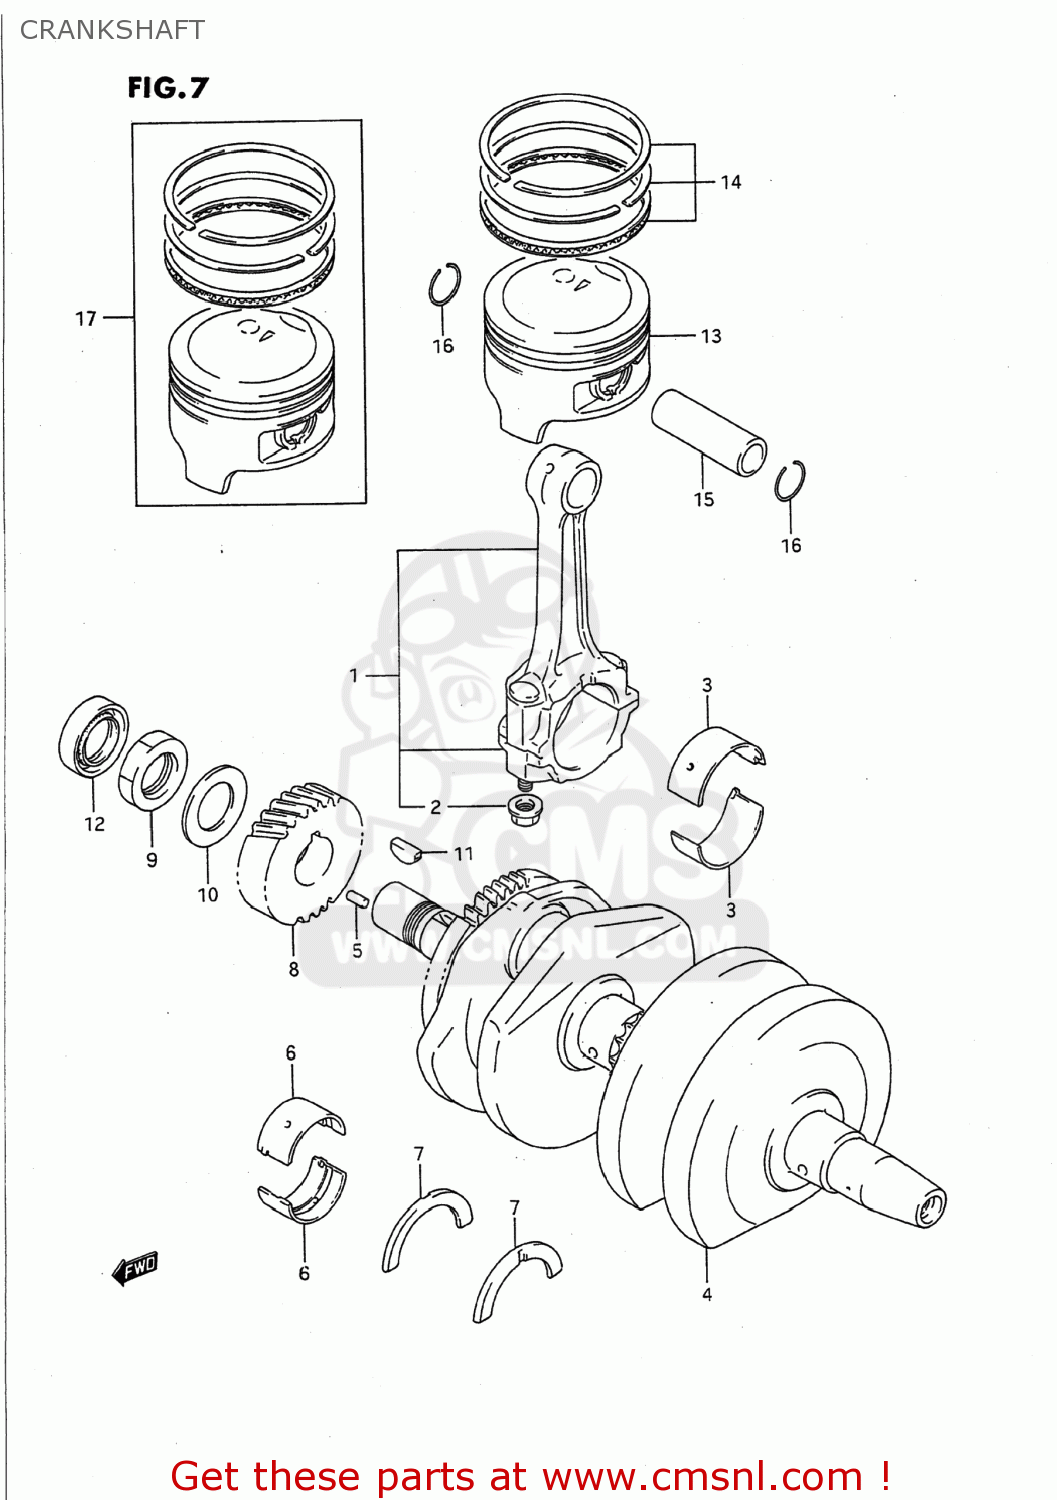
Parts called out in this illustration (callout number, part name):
1	ROD ASSEMBLY,CONNECTING
2	NUT
3	BEARING,CRANK PIN
4	CRANKSHAFT
5	PIN
6	BEARING,CRANKSHAFT(GREEN)
7	BEARING,CRANK THRUST
8	GEAR,PRIMARY DRIVE NO.28
9	NUT
10	WASHER
11	KEY
12	SEAL,OIL(22X40X8)
13	PISTON
14	RING SET,PISTON
15	PIN,PISTON (18MM)
16	CIRCLIP
17	PISTON SET(OS:0.5)
